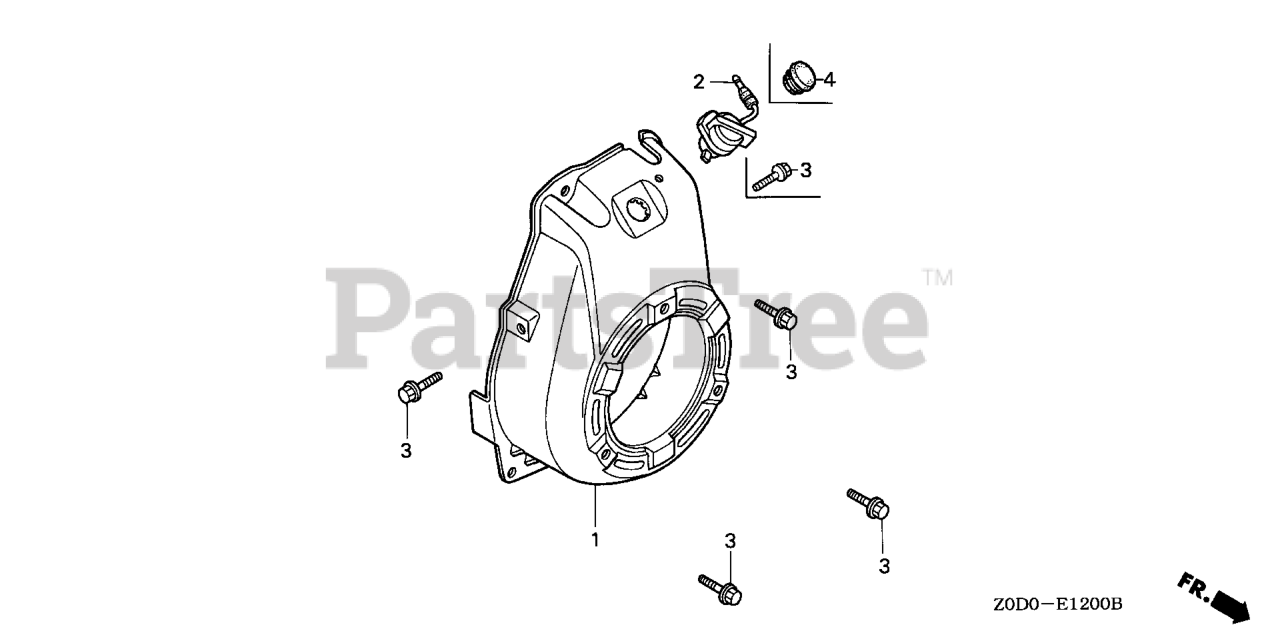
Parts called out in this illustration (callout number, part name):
1	COVER, FAN *NH1* (BLACK)
1	COVER, FAN *R280* (POWER RED)
2	SWITCH ASSY., ENGINE STOP Use from Engine SN 2092216 to 2359126.
3	BOLT, FLANGE (6X14)
